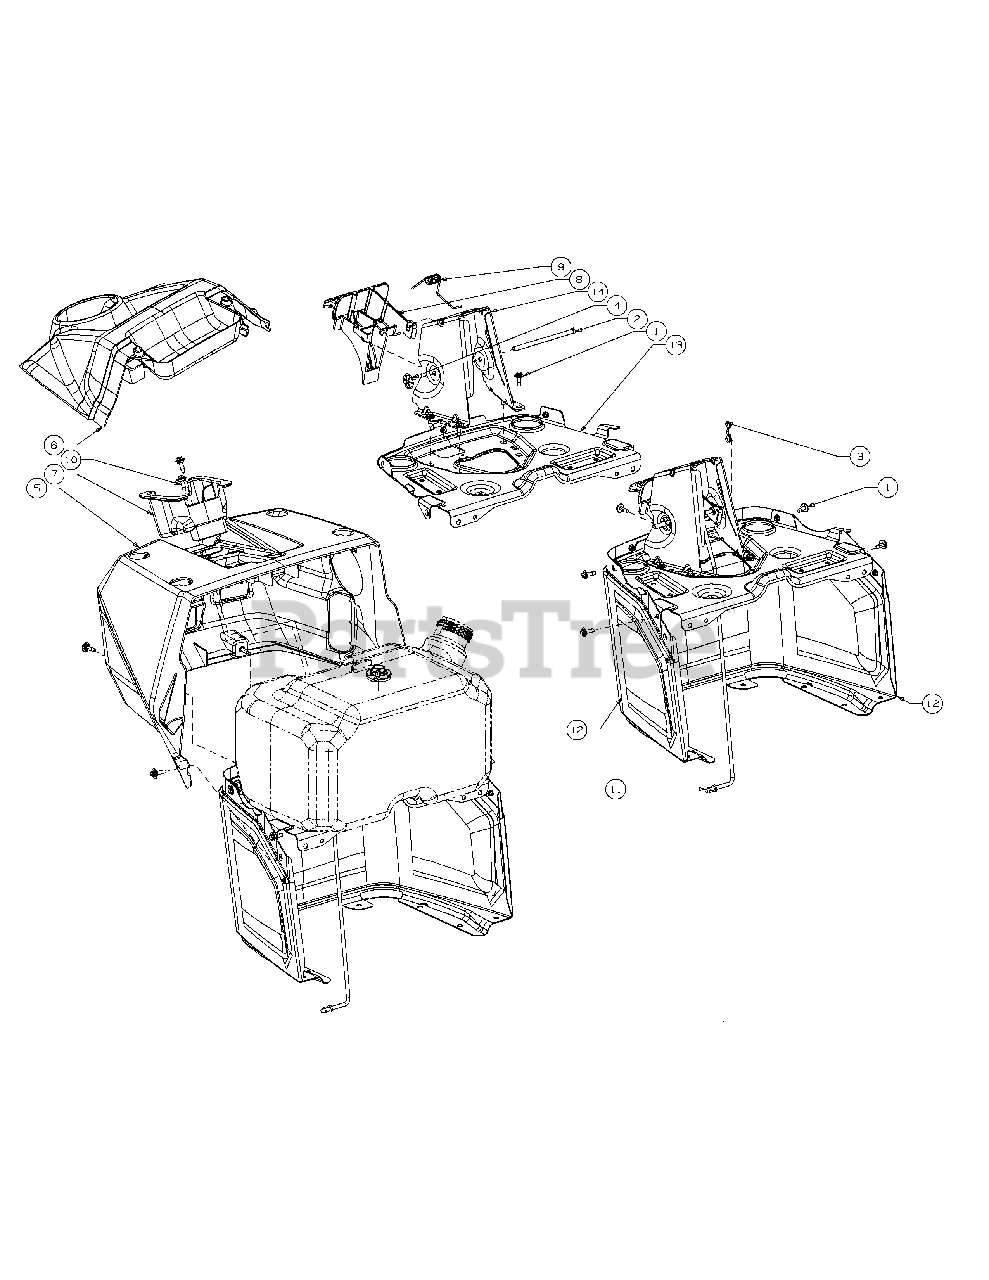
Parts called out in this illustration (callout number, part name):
1	Screw-Hxacrnwsh M6-
2	Pin-Crus/Brake Lever
3	Pin-Cotter
4	Nut:Push-On:.25 Dia
5	Dash:Upr:C Sty
6	Dash:Cap:C Sty
8	Lever-Cruise/Brake Dash
9	Spring-Torsn Crus/Brake Lvr
10	Scr-Shldr M6-1 .3
11	Rod-Cruise/Brake
12	Dash-Lower
13	Plate-Dash/Fuel Tnk
14	Brkt-Strg Brg Mtg Dash
14	Bearing-Steering Shaft
